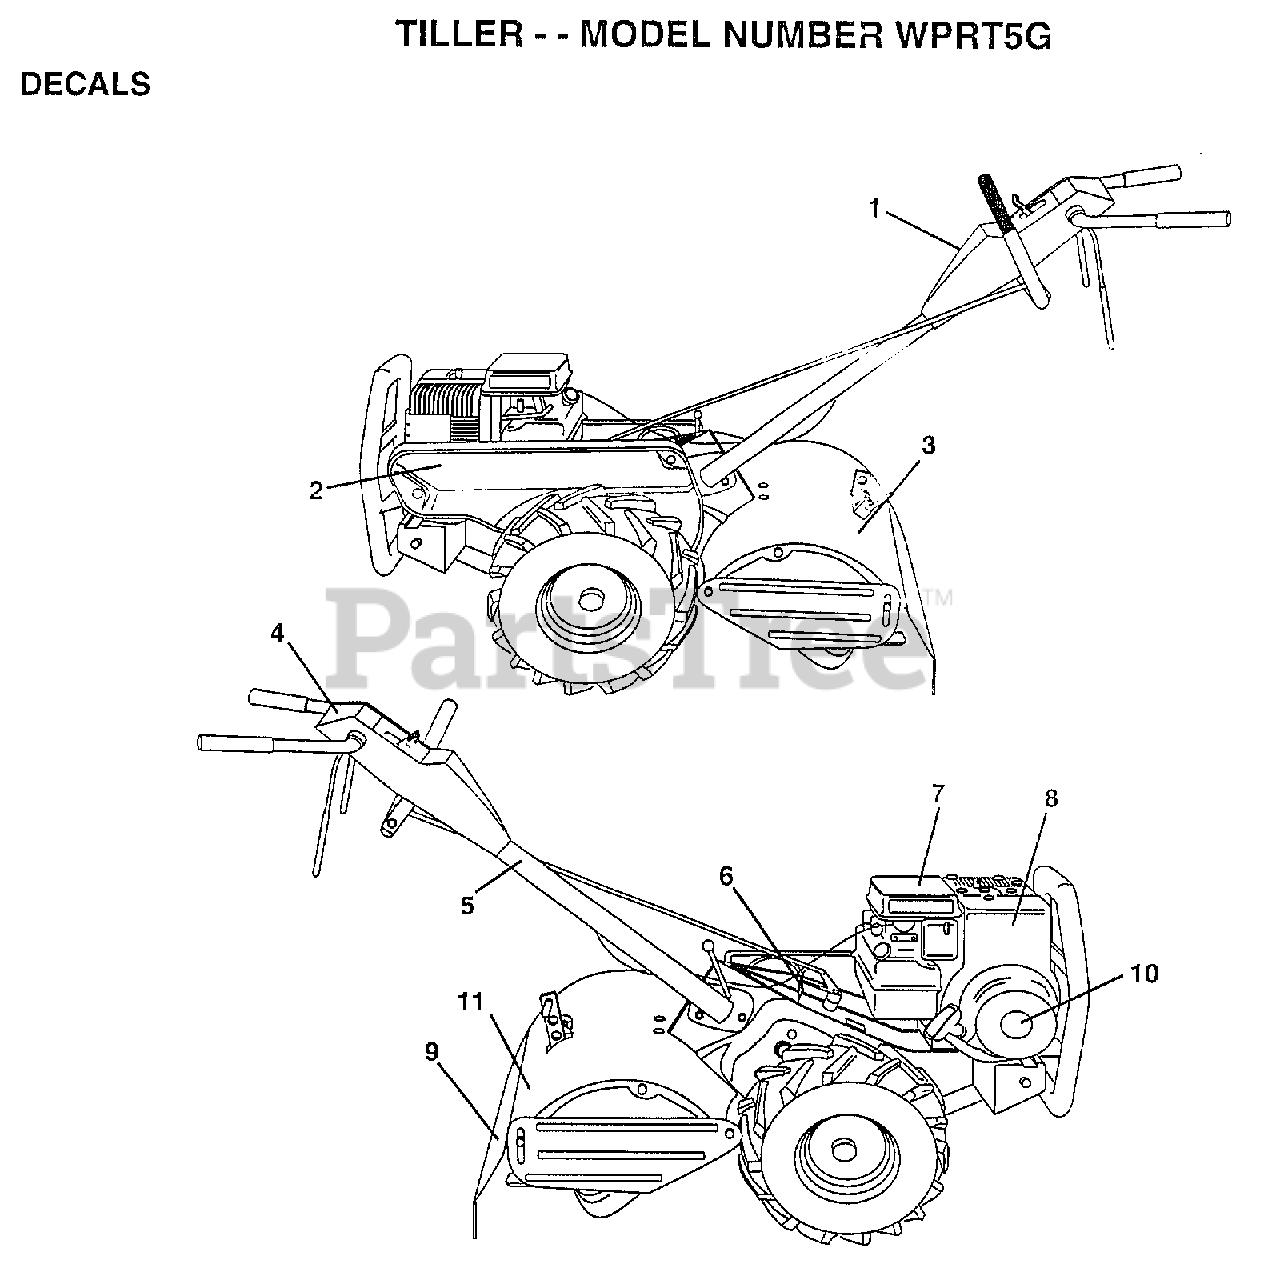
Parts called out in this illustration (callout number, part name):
1	DECAL.PNL.CONTROL
2	DECAL.GD.BELT.5HP
3	DECAL.SHLD.TINE
4	DECAL.INSTRUCTION
5	DECAL TI
6	DECAL CRT
8	DECAL, BRIGGS & STRATTON
9	DECAL TI
11	DECAL.TINE.SHIELD
